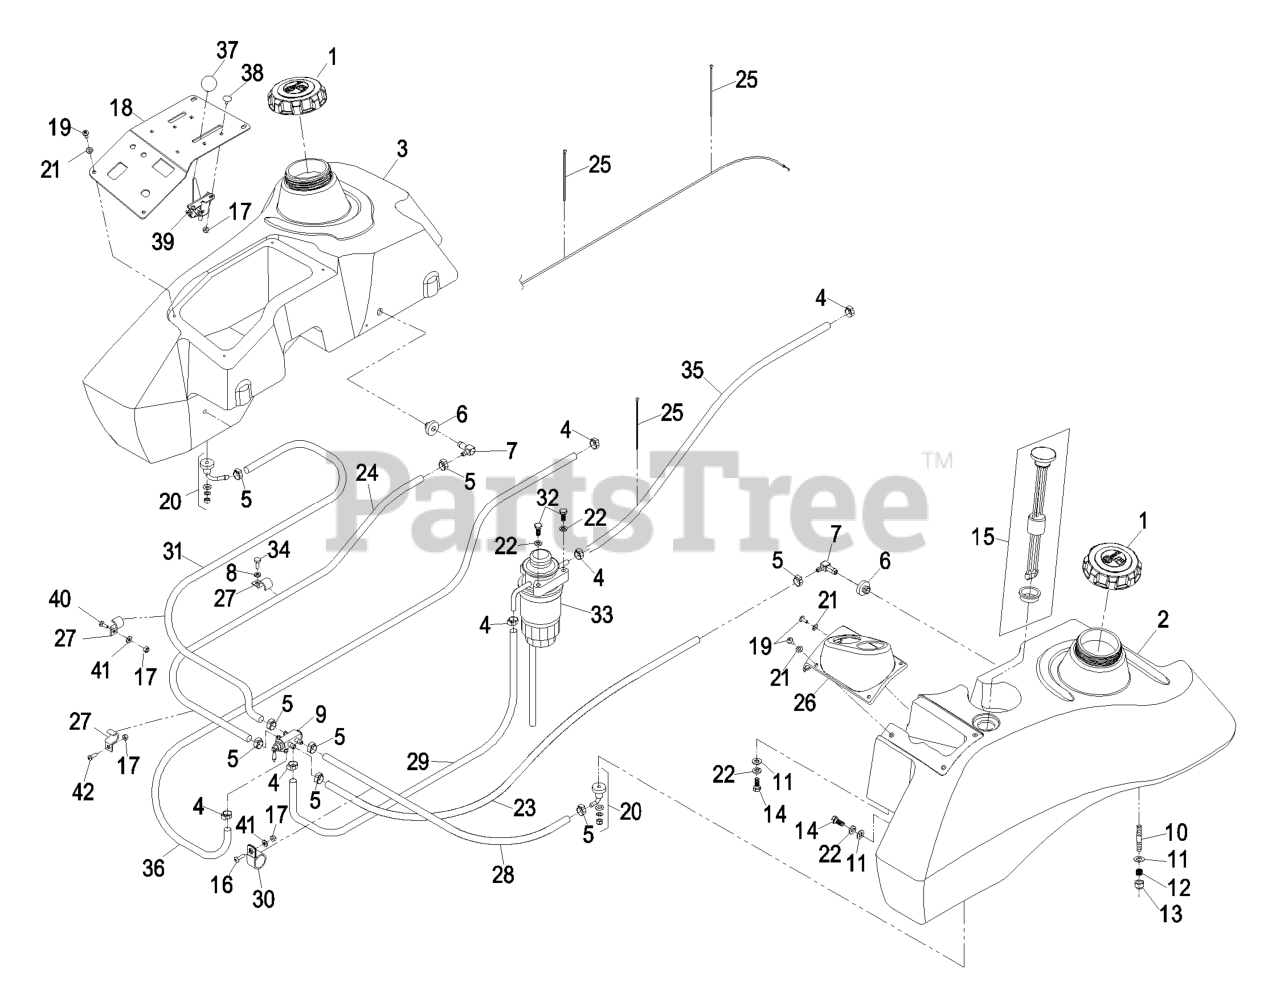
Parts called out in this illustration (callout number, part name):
4	CLAMP-HOSE, FUEL
5	CLAMP-HOSE, FUEL
7	ELBOW-90 DEG
8	WASHER-LOCK
9	VALVE-FUEL, DUAL FLOW
10	STUD
11	WASHER-PLAIN
12	SPRING-TANK, FUEL
13	NUT-LOCK, NI
14	SCREW-HH
15	KIT, CT FUEL GAGE REPL.
16	SCREW-HEAD, TRUSS
17	NUT-LOCK, NI
19	SCREW-PTH
20	FITTING-FUEL, BULKHEAD
21	WASHER-SPRING
22	WASHER-LOCK
25	TIE-PLASTIC
26	BEZEL, GAGE XP LH TANK
27	CLIP-HALF, LOOM
28	HOSE-FUEL
29	HOSE-FUEL
30	CLIP-LOOM
32	SCREW-HH
33	Briggs & Stratton P/N 820311 Fuel Filter
34	SCREW-HH
36	HOSE-OVERFLOW
37	KNOB-BALL
38	BOLT-CARR
39	CABLE-THROTTLE
40	BOLT-CARR
41	WASHER-FLAT
42	SCREW-PPH
